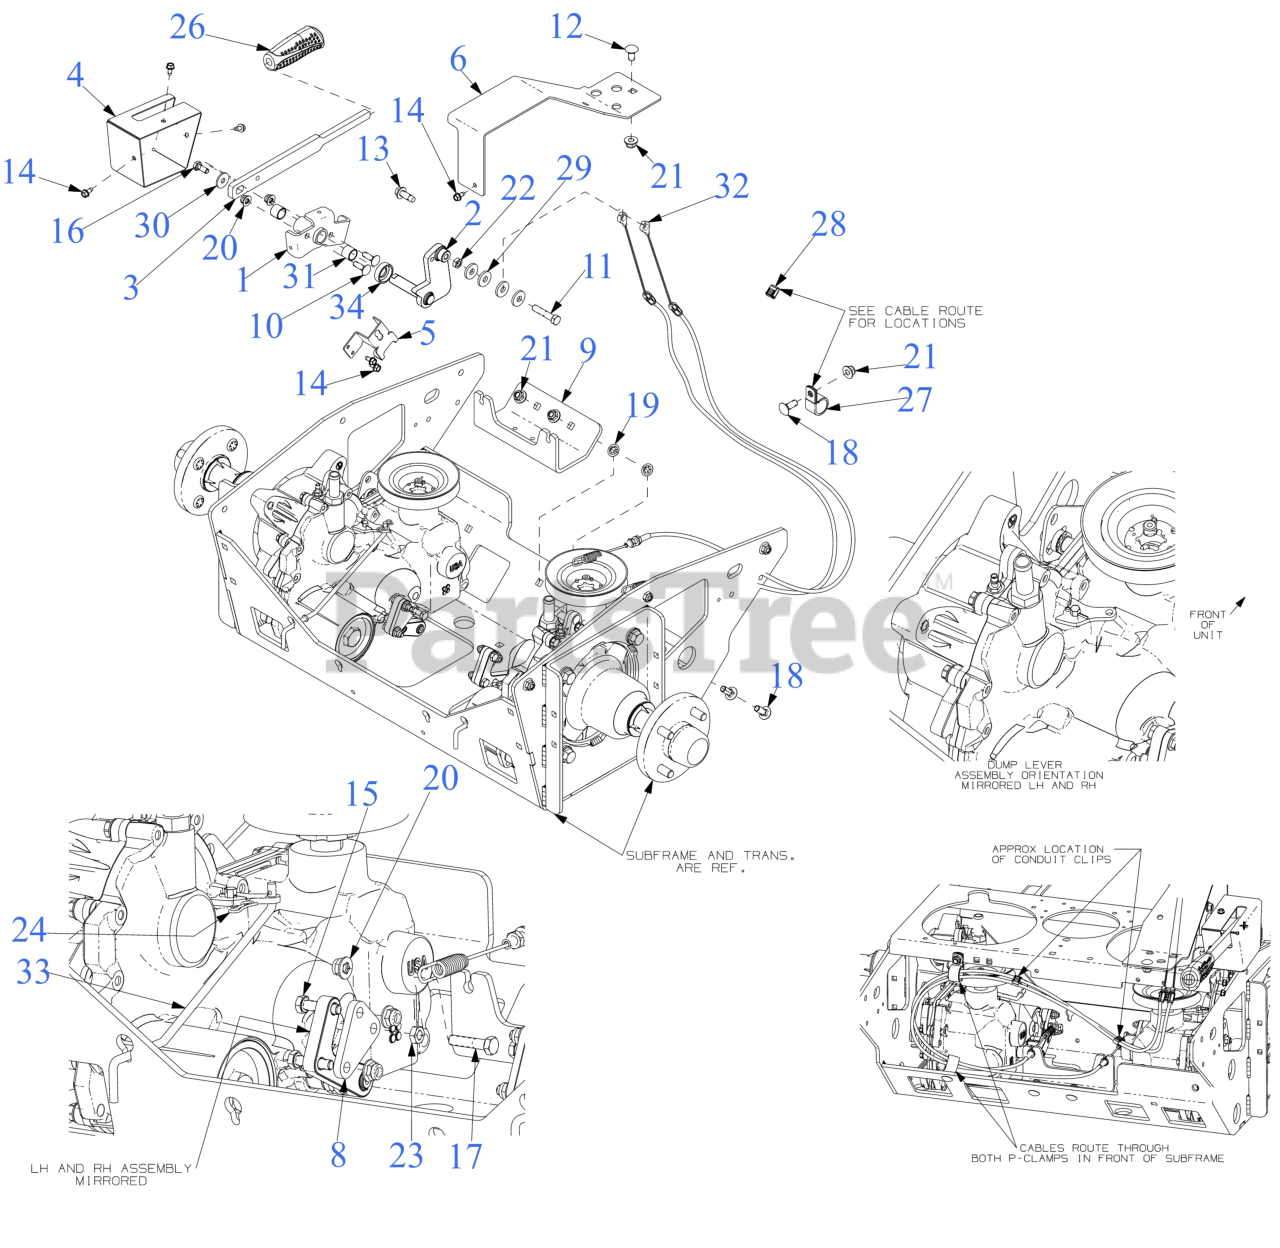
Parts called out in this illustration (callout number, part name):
1	PIVOT TUBE ASSEMBLY
2	BRAKE PIVOT SHAFT
5	3-POLE SWITCH BRACKET
6	BRAKE LEVER COVER
8	BRAKE ARM PLATE
9	BRAKE CABLE MOUNT PLATE
10	CARRIAGE BOLT 5/16-18 x 1.00
11	HEX SCREW 3/8-16 x 1.75 GR5
12	CARRIAGE BOLT 3/8-16 x .750 GR5
13	SCREW 3/8-16 x 1
14	SCREW 1/4-20 X.500
15	SCREW 5/16-18 x 1.25 GR5
16	SCREW 5/16-18 x .750
17	BOLT 5/16-18X1.375 GR5
18	CARRIAGE BOLT 3/8-16 x 1.00 GR5
20	FLANGE LOCK NUT 5/16-18
22	HEX JAM NUT 3/8-16 GR5
23	HEX NUT TOP LOCK 5/16-18 GR 8
24	BOW TIE COTTER PIN 1/4-5/16
27	HOSE CLAMP 1.0"
28	CABLE CLIP
29	FLAT WASHER .385 x 1.00 x .135
30	FLAT WASHER 1.0 OD:.331 ID
31	SLEEVE BEARING
32	PARK BRAKE CABLE
33	BYPASS ROD
